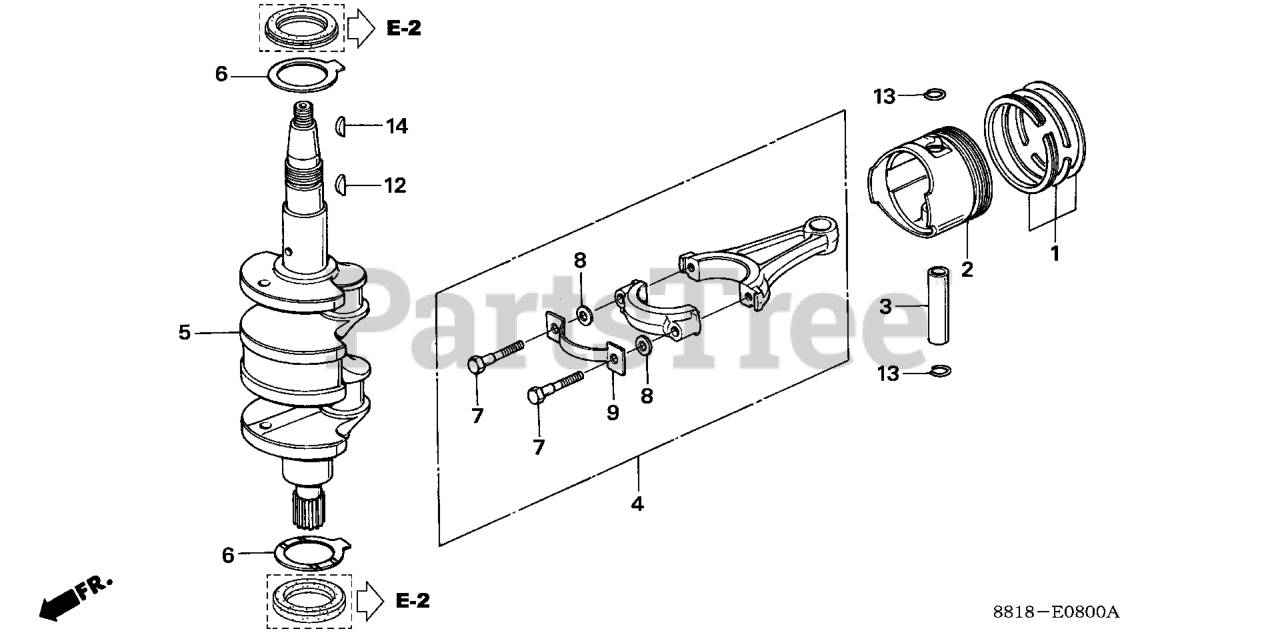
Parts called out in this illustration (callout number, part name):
1	RING SET, PISTON (2SET) (STD)
3	PIN, PISTON
4	ROD ASSY., CONNECTING
5	CRANKSHAFT, R.
6	BEARING, CRANKSHAFT THRUST
7	BOLT, CONNECTING ROD
8	WASHER (6MM)
9	WASHER, LOCK
12	KEY, SPECIAL (16X15)
13	CLIP, PISTON PIN (14MM)
14	KEY, WOODRUFF (16X15)
